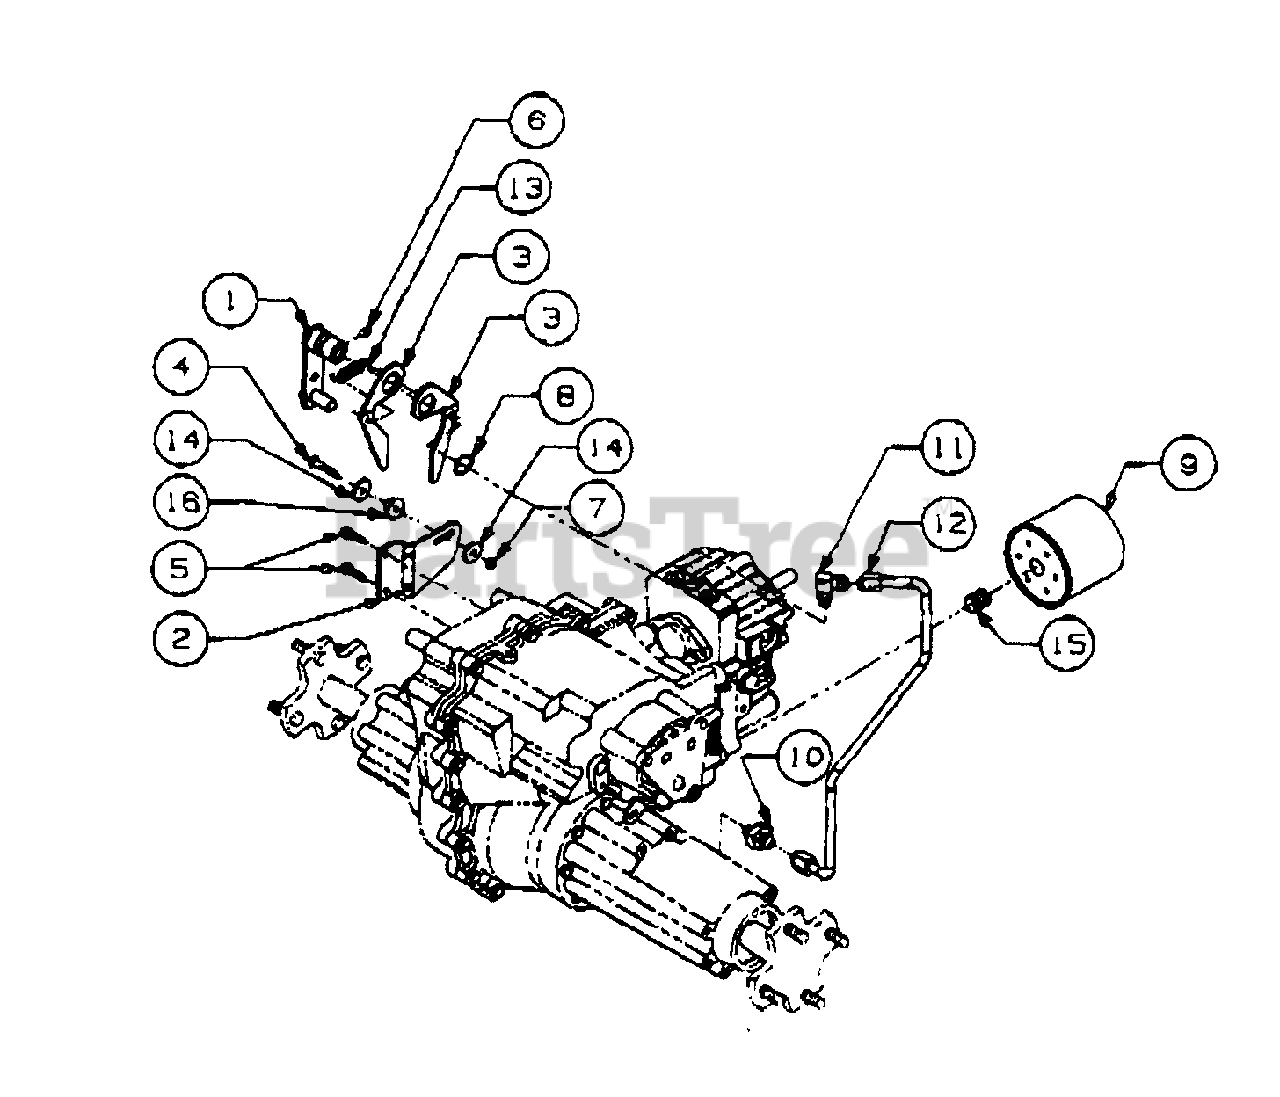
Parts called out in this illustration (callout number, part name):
1	Arm Assy, Control
2	Bracket, Hydro Neutral
3	Arm, Neutral
4	Screw, Hex Cap, 1/4-20 x 1.25 Lg
5	Screw, Hex Wash TT-Tap, 1/4-20 x 1.0 Lg
6	Screw w/Patch, Set
7	Nut, Hex Top Lock, 1/4-20
8	Ring, Snap, .875 Shaft
9	Filter, Oil
10	Connector, Tube 37 Deg w/O-ring
11	Elbow, Adjustable w/O-Ring
12	Tube, Pickup
13	Spring, Extension, .50 OD x 1.97 Lg
14	Washer, Flat, .25 x .93 x .120 Thk
15	Nipple, Oil Filter
16	Spacer, Centering
